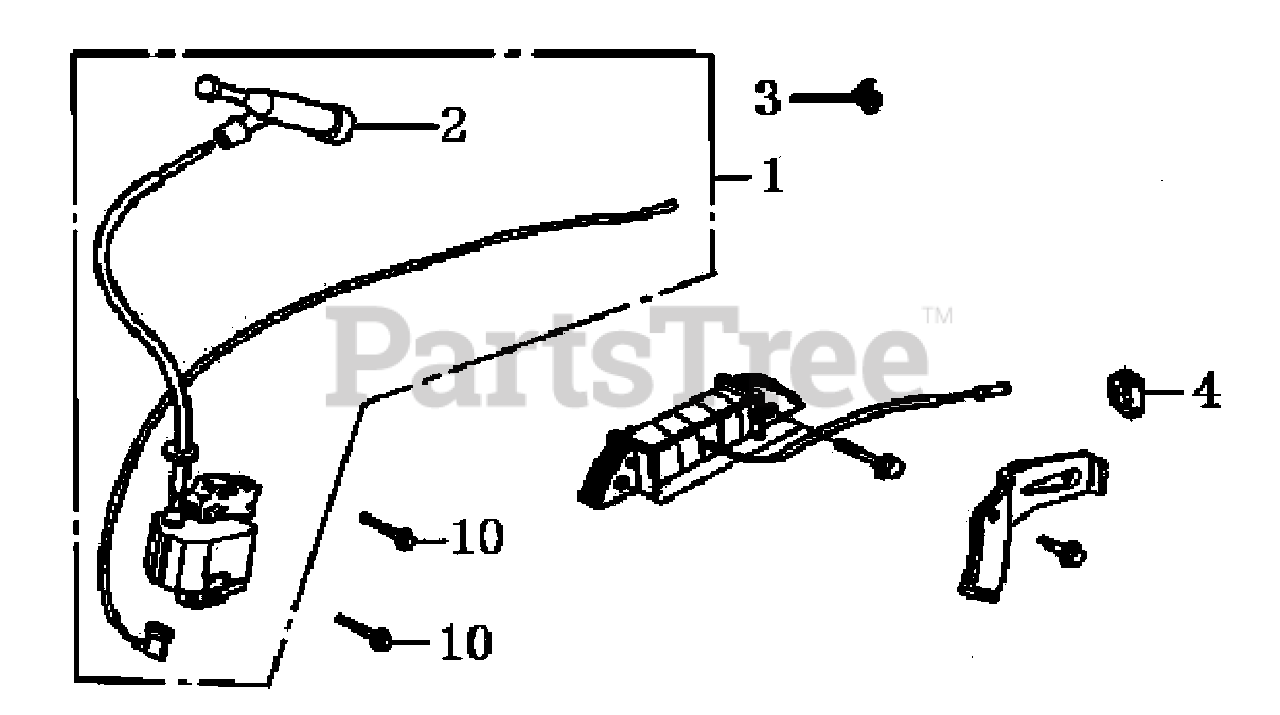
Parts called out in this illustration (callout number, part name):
1	COIL ASSY., IGNITION
2	CAP ASSY., NOISE SUPPRESSOR
3	HOLDER, STOP SWITCH
4	GROMMET, CORD
10	BOLT, FLANGE
